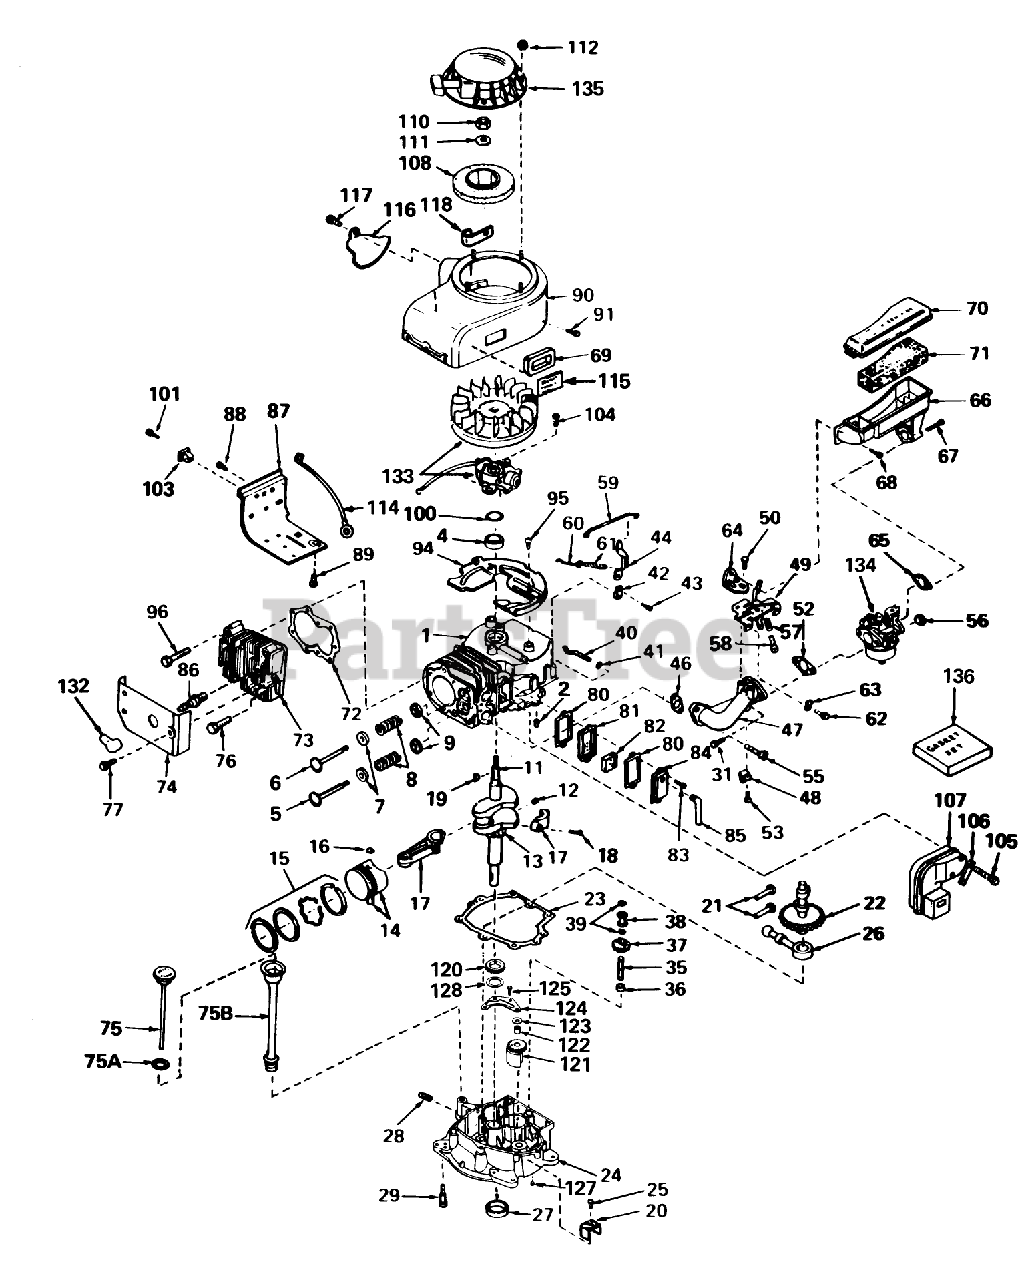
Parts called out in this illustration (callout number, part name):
1	Cylinder Assy. (Incl. Nos. 2 4)
2	Pin-Dowel
4	Oil Seal
5	Valve, Intake (Std.) (Incl. Ref. #58)
5	Valve, Intake (1/32" oversize) (Incl. Ref. #58)
6	Valve, Exhaust (Standard)(Incl. No. 9)
6	Valve, Exhaust (1/32" oversize)(Incl. No. 9)
7	Cap-Spring, Valve
8	Spring-Valve
9	Keeper-Spring, Valve
11	Crankshaft Assy. (Incl. Nos. 12, 13 120)
12	Pin, Groove
13	Gear, Crankshaft
14	Piston, Pin Ring Assy. (Std.) (Incl. Nos. 15 16)
14	Piston, Pin Ring. Assy. (.010 oversize) (Incl. Nos. 15 16)
14	Piston, Pin Ring Assy. (.020 oversize) (Incl. Nos. 15 16)
15	Ring Set (Std.)
15	Ring Set (.010" OS)
15	Ring Set (.020" OS)
17	Rod Assy., Connecting (Incl. Nos. 10 18)
18	Bolt, Connecting Rod
19	Key-Flywheel
20	Screen, Oil Filter
21	Lifter-Valve
22	Camshaft (Mech. Compression Release)
23	Gasket, Cylinder Cover
24	Flange, Mounting (Incl. Nos. 20, 25, 27, 28, 35 127)
25	Screw
26	Pump, Oil
27	Seal, Oil
28	Plug, Drain
29	Screw (1/4-20 x 1-1/4)
31	Screw (1/4-28x1)
35	Shaft, Governor
36	Spacer
37	Governor Gear ASM
38	Spool-Governor
39	Ring-Retaining
40	Rod, Governor
41	Washer-Flat
42	Clamp-Lever, Governor
43	Screw
44	Governor Lever
46	Gasket-Intake
47	Pipe, Intake
48	Bracket, Intake Pipe
49	Control Assy., Speed (Incl. Nos. 57 58)
50	Screw (10-24 x 9/16)
52	Gasket, Carburetor
53	Screw (1/4-20 X 5/8)
55	Screw (T-30, 5/16-18x1-3/32)
56	Nut and Lock Washer (1/4-28)
57	Spring-Compression
58	Screw
59	Link, Throttle
60	Link Governor Spring
61	Spring Governor
62	Screw (10-32 x 3/8)
63	Conduit
64	Bracket, Air Cleaner
65	Clutch Arm Assembly
66	Body, Air Cleaner
67	Screw Fil Hd.
68	Screw, Fil. Hd. Sems
69	Gasket, Air Cleaner
70	Cover, Air Cleaner
71	Element, Air Cleaner
72	Gasket-Cylinder Head
73	Head Cylinder
74	Cover, Cylinder Head
75	Dipstick, Oil (Incl. No. 75A)
75A	O-Ring
75B	Tube, Oil Filler
76	Screw (5/16-18x1-1/2)
77	Screw (1/4-20 x 1/2)
80	Gasket-Breather
81	Body-Breather
82	Element-Breather
83	Screw
84	Cover-Valve
85	Tube-Breather
86	Plug, Spark (J17LM or equiv.)
86	Plug, Spark (Champion RCJ-8)
87	Extension, Blower Housing
88	Screw
89	Screw
90	Housing, Blower
91	Screw, Hex Hd.
94	Baffle Blower Housing
95	Screw (1/4-20x19/32)
96	Screw (5/16-18x3/4)
100	Gasket Stator
101	Screw
103	Grommet
104	Screw
105	Screw, Hex Hd.
106	62513 SNWTHWR W/284
107	Muffler
108	Hub Screen Assy., Starter
111	Washer
112	Nut and Lock Washer (1/4-28)
114	Wire, Ground
115	Decal, Instruction
116	Screw
117	Screw (8-32 x 3/8)
118	Clip Oil Tube
120	Gear, Crankshaft Counterbalance
121	Weight, Counterbalance Assy., (Incl. No. 122)
122	Bearing, Needle
123	Washer, Thrust
124	Bracket, Shaft Retaining
125	Screw (10-24 x 9/16)
127	Plug-Pipe
128	Washer, Thrust
132	Cover-Spark Plug
133	Magneto (The complete magneto is not available as an assembly. The magneto number is shown for reference purposes only. Order component parts individually, as shown in parts list.)
134	Carburetor (Incl. No. 52)
135	Starter, Rewind
136	Gasket Set
